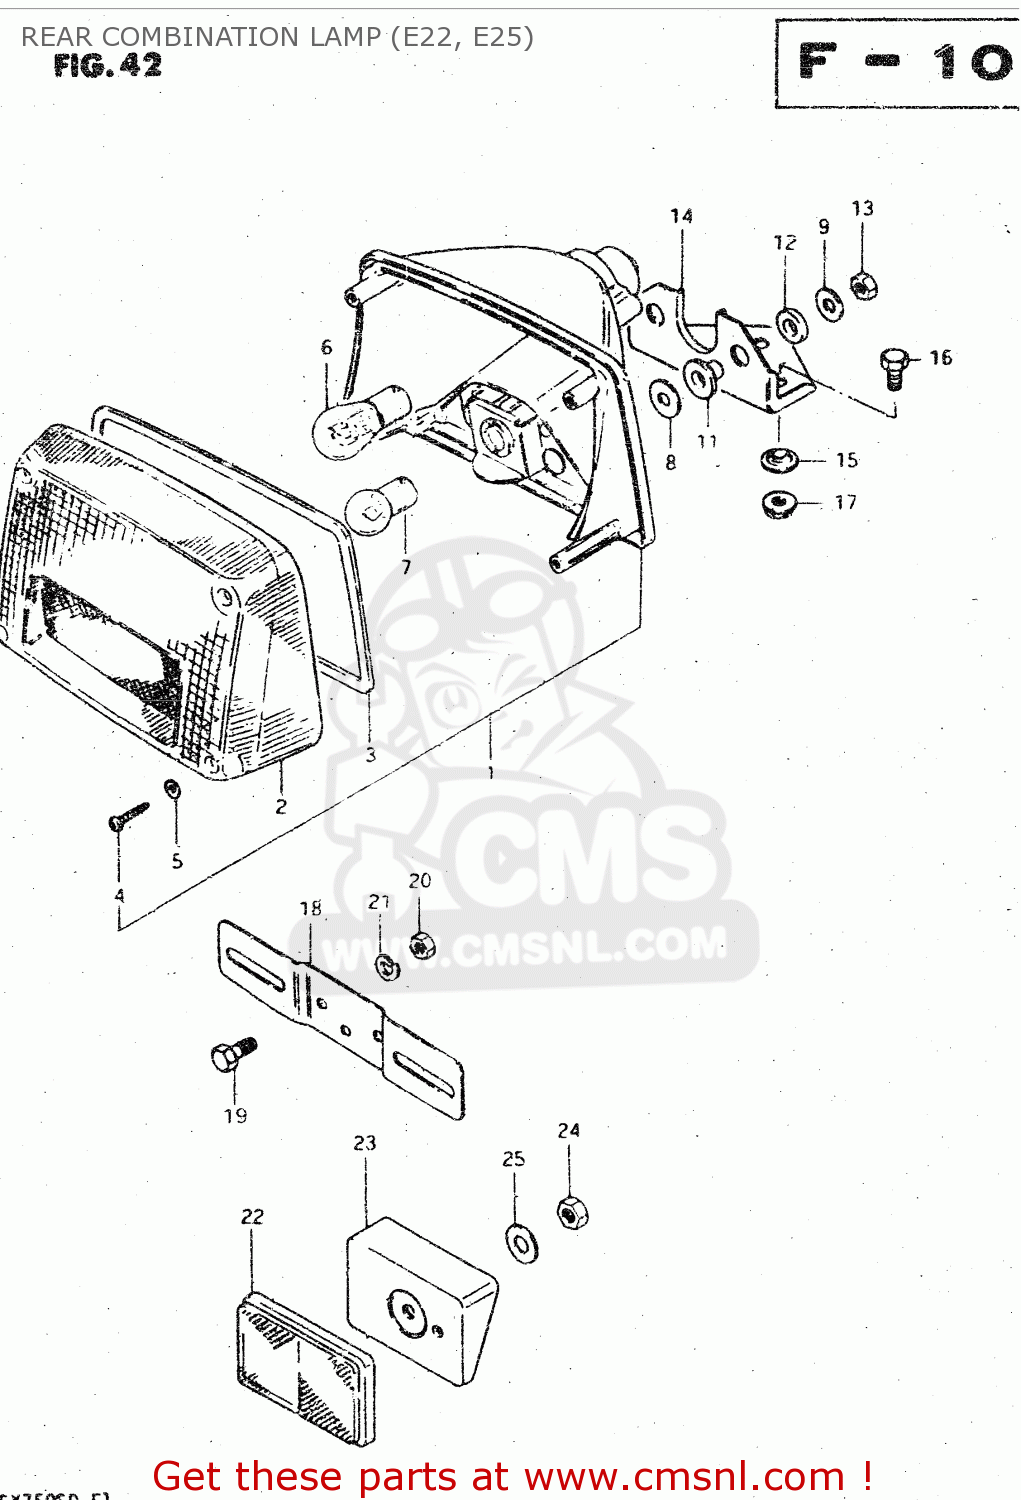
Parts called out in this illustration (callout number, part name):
1	LAMP ASSY, TAIL
2	LENS
3	GASKET (NAS)
4	SCREW,REAR COMBINATION LAMP
5	GASKET (NAS)
6	BULB(12V21/5W)
7	BULB
8	WASHER
9	WASHER(6,5X22X1.6)
10	SPACER(6.1X9X7.5)
11	CUSHION
12	CUSHION
13	NUT 6MM
14	BRACKET,RR COMBINATION LAMP
15	WASHER
16	BOLT, UPPER
17	NUT 6MM
18	PLATE,RR LICENSE
19	BOLT
20	NUT
21	LOCK WASHER
22	REFLECTOR,REFLEX
23	SPACER
24	NUT
25	WASHER(5.2X16X1)
